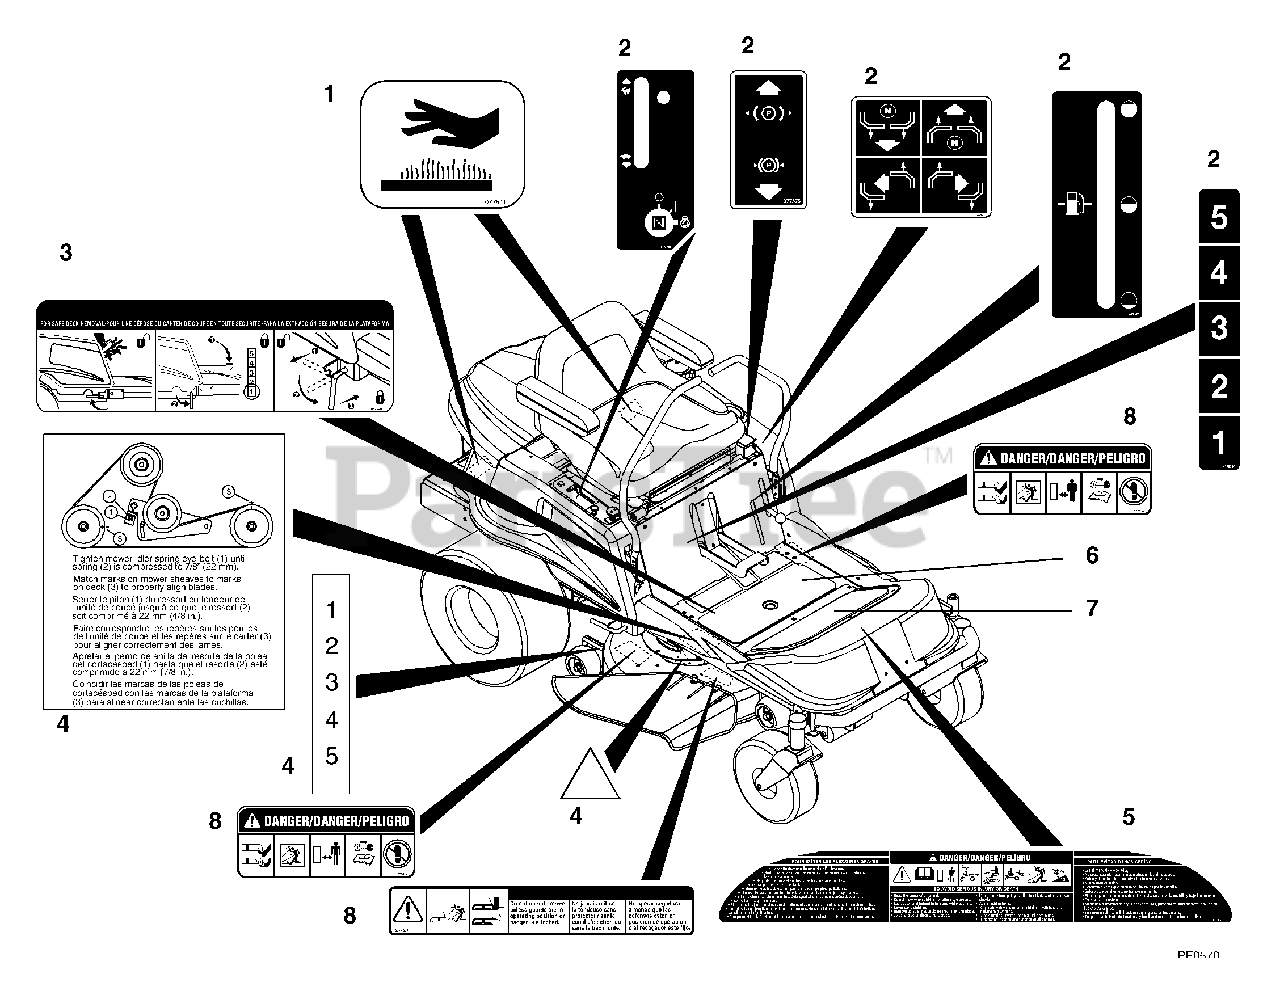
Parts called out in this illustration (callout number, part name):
1	Decal, Hot Surface
2	Decal-Instructional Set
3	Decal, Safe Deck Removal
4	Decal-Set 42" Deck
5	Decal, Bilingual Danger
6	Non-Skid Cover
7	Non-Skid Cover
8	Decal-Set Deck
